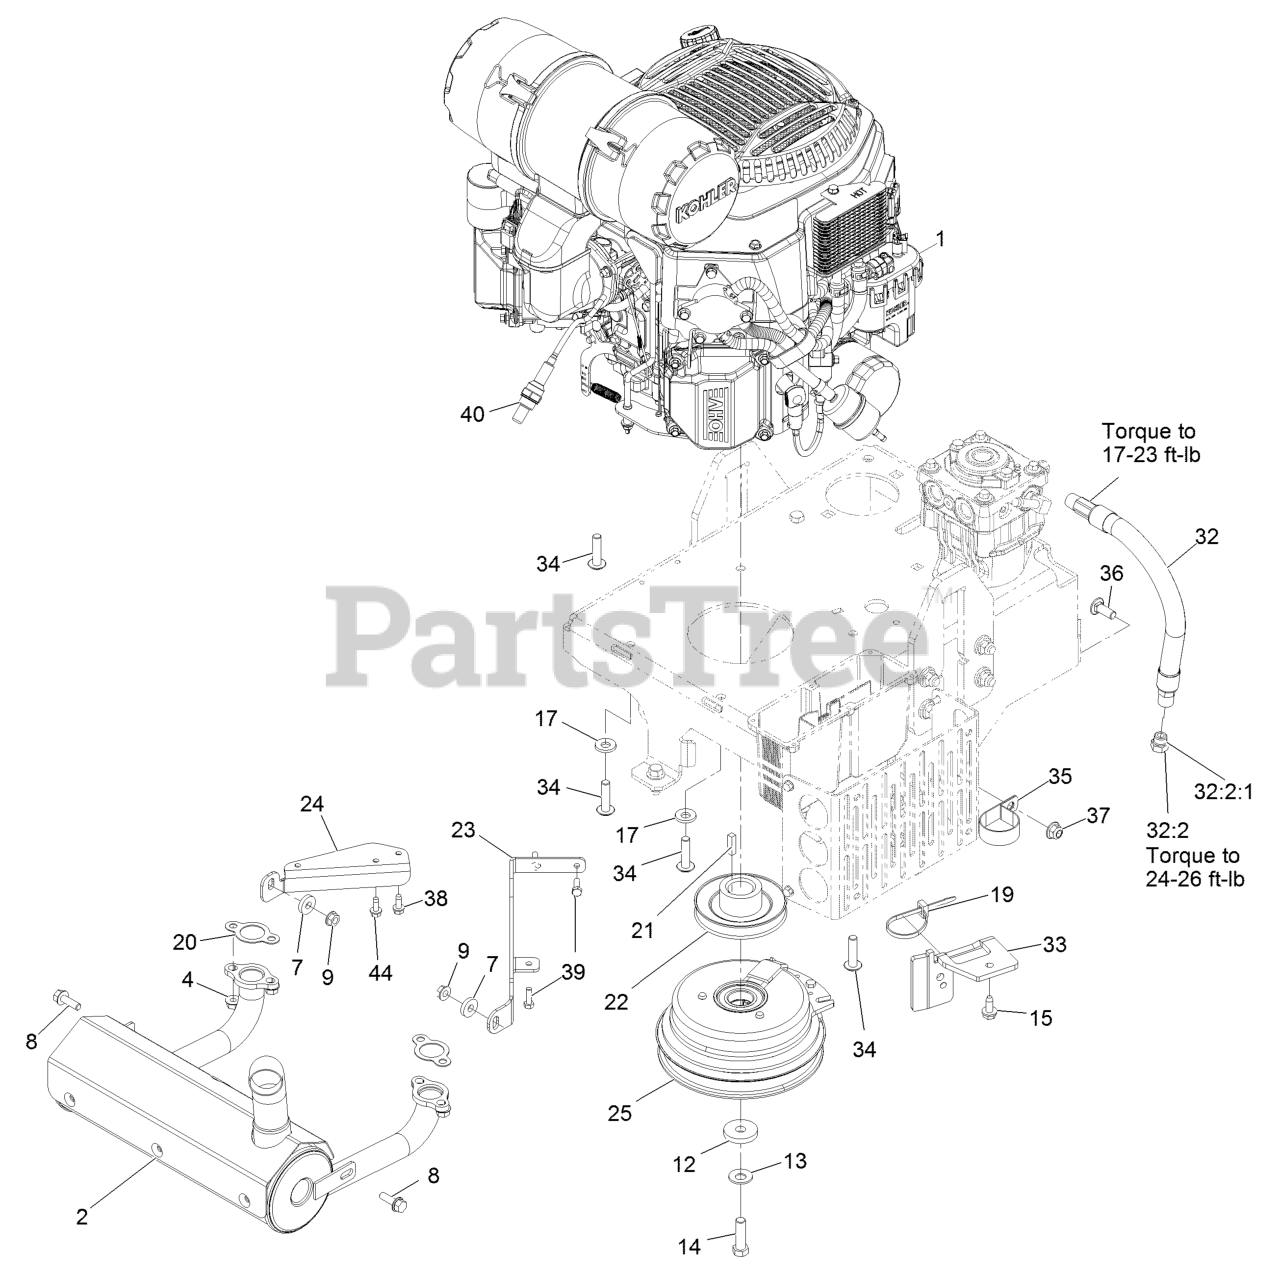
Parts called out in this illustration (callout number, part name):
4	NUT-FLANGE
8	SCREW-HHF
12	WASHER
13	WASHER-SPRING
14	SCREW-HH
15	Screw-HWH 5/16-18 X 3/4 Tf
17	WASHER-BELLEVILLE
19	TIE-CABLE
20	GASKET-EXHAUST
23	MOUNT, MUFFLER-LT
24	MOUNT, MUFFLER-RT
25	CLUTCH-200 FT-LB, 1.125 B
32	OIL DRAIN HOSE ASM
32:2	PLUG-HH
32:2:1	O-RING
33	BRACKET-ANCHOR, CLUTCH
34	SCREW-BHTF
35	CLAMP-R
36	SCREW-CARR
37	NUT-HF, NI
38	SCREW-HWHTF
39	SCREW-HH M6-1 X 20Mm W/Patch
40	SENSOR-OXYGEN
44	SCREW-HWHTF
